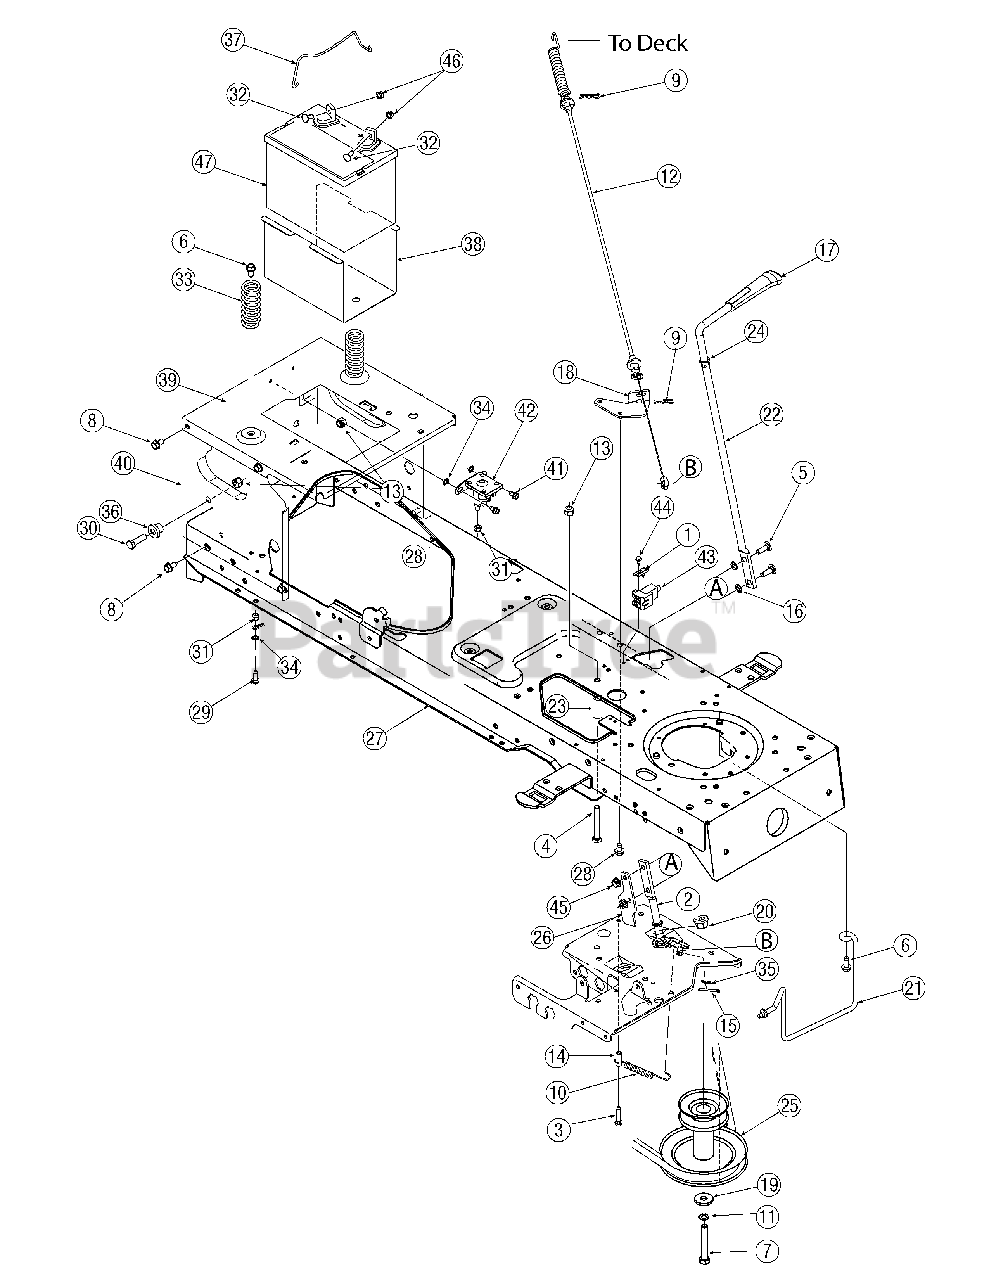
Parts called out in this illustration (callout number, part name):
1	Plate, Switch
2	Lever Assembly, Engagement
3	Screw, 1/4-20 x 1.500
4	Screw, 3/8-16, 2.50
5	Screw, Carriage, 5/16-18, 1.00
6	Screw, 5/16-18 x.750
7	Screw, 7/16-20, 3.25, Gr5
8	Screw, 5/16-12, 0.750
10	Extension Spring,.38OD x 3.9LG
11	Lock Washer, 7/16
12	Deck Engagement Cable
13	Nut, Flange Lock, 3/8-16, Gr5
14	Spacer, .260 x .372 x 1.030LG
15	Pin, Cotter, 1/8 x 1.25
16	Nut, Speed,.3125 ID
17	Knob, PTO
20	Bearing, Flange, .500 ID
21	Keeper Rod, Belt
22	Engagement Handle, Deck
23	Spacer,.385 ID x.635 OD x 1.54
24	Flat Washer, .510 x .750 x .033
25	Pulley, Engine, 3.39 x 6.12
29	Screw, 1/4-20, 0.750
30	Screw, 3/8-16, 1.25, Gr5
31	Nut, Flange Lock, 1/4-20, GrF
32	Screw, Carriage, 1/4-20,.75
33	Spring, Compr. , 1.28 OD x 3.125 x .033
34	Washer, Lock, 1/4, External
35	Flat Washer, .344 x .688
36	Spacer, Shoulder,.38 x 1.0
37	Hold Rod, Battery
42	Solenoid, 12V, 100 Amp
43	Switch, Interlock
44	Screw, #10-16,.50
45	Nut, Flange, Lock Nut, 5/16-18
46	Nut, Sems, 1/4-20
47	Battery, 190 CCA
